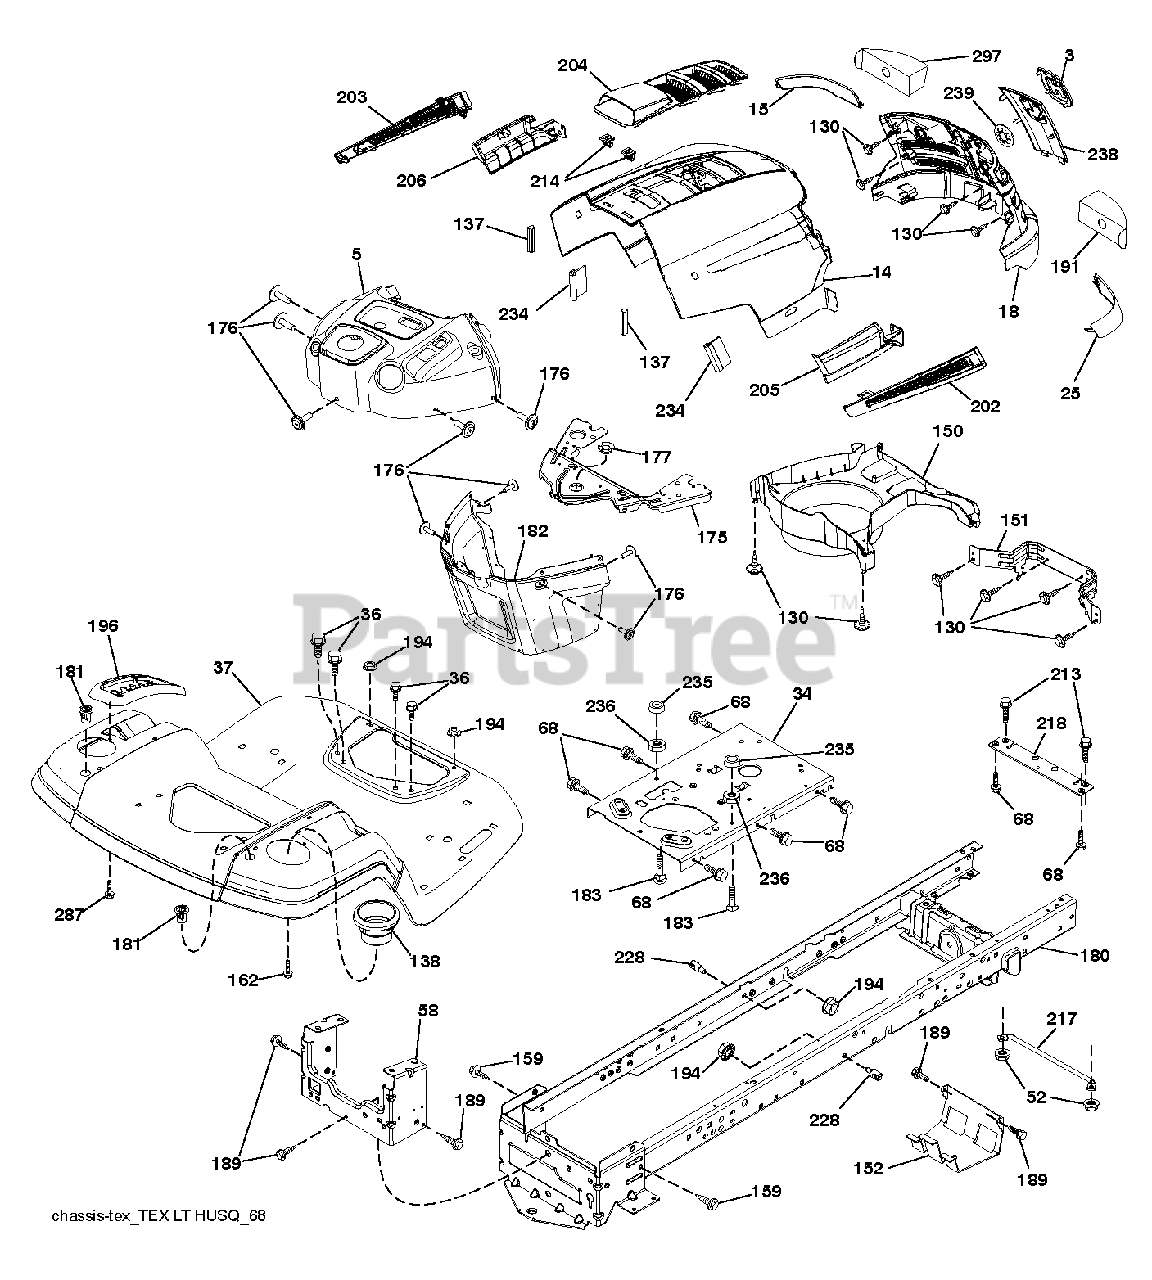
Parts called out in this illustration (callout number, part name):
3	LOGO.HUSQ.GT.LT.CROWN.H
5	DASH.UP.HU.LT.CBL.CLTCH.CHG.PT
14	HOOD.HUSQVARNA.LT.ORANGE
15	LENS.HUSQVARNA LT.RH
18	GRILLE.SVC.HUSQVARNA.GREY
25	LENS.HUSQVARNA LT.RH
34	PLATE.ENGINE.WELDED.CHASSIS
36	SCREW 5/16"
37	FENDER.TLT.PDL.CNTRL.W/CPH.ORG
52	LOCKNUT
58	DRAWBAR UPPER 2PC SMALL FENDER
68	SCREW LT
130	SCREW.#10 X 0.750.BOS
137	BUMPER DASH
138	HOLDER.CUP.LT.GREY
151	BRACKET PIVOT
152	SHIELD.BROWNING.W/TEX
159	SCREW, 3/8-16X3/4
162	SCREW.HI-LO.CONSOLE
175	CROSSMEMBER
176	SCREW.#10-24X5/8.RN.QU
177	BUSHING STEERING
180	CHASS.WLDMNT.TL.12GA/2P.48/54
181	BUSHING.MNT.FEND.CRGO.TEX.49
182	DASH.LOWER.PREDATOR LT
183	BOLT.5/16-18X1-1/4 FULL THD
189	SCREW
191	INSERT.REFLECTIVE.RH.
194	NUT LOCK HEX FLANGE 5/16-18
196	DECKLFT.CONSOL FULL ASSM GREY
202	VENT.SIDE.HUSQVARNA.LT.RT
203	VENT.SIDE.HUSQVARNA.LT.LFT
204	SUBASM.TOP.VENT.HUSQ.LT
205	SKIRT.SIDE.HUSQVARNA.LT.RT
206	SKIRT.SIDE.HUSQVARNA.LT.LEFT
213	BOLT
214	CLIP.RETAINER.TINNER.
217	ROD.PIVOT.HOOD
218	X-PIECE.HOOD.STOP.NON/
228	STUD.FASTNER.W/ANTI-ROTATE
234	BUMPER.HOOD.TEX.HUSQVARNA
235	SPACER FENDER
236	NUT.CENTERLOCK.5/16-
238	TRIM.HUSQ LT.668
287	SCREW 1/4X20
297	INSERT REFLECTIVE
